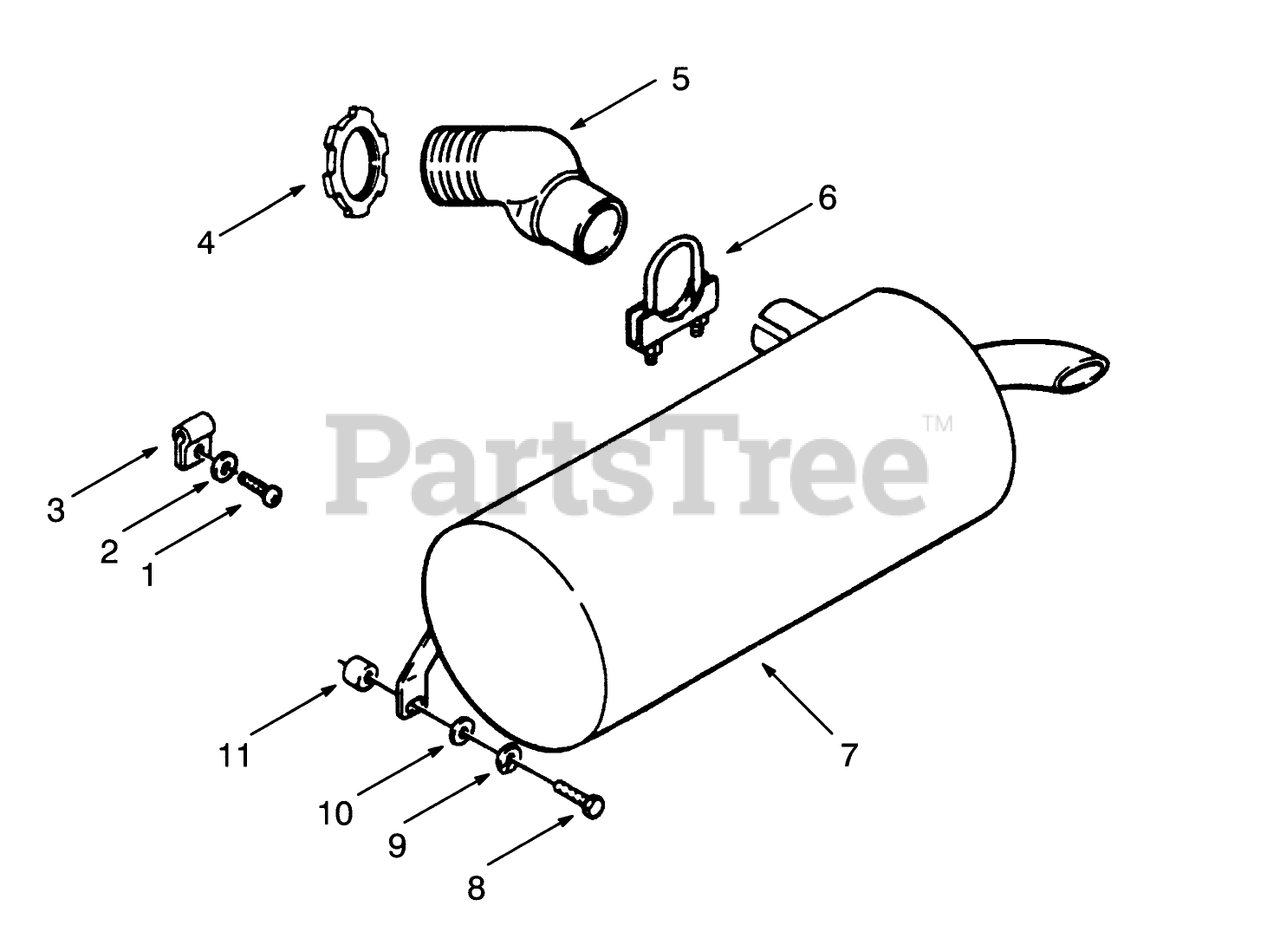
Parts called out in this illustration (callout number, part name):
1	KOHLER X-67-83
2	KOHLER X-25-72
3	KOHLER 48-154-01
4	KOHLER AC-1536
5	KOHLER47-054-01
8	SCREW-HH
9	WASHER-LOCK
10	WASHER-FLAT
11	SPACER
